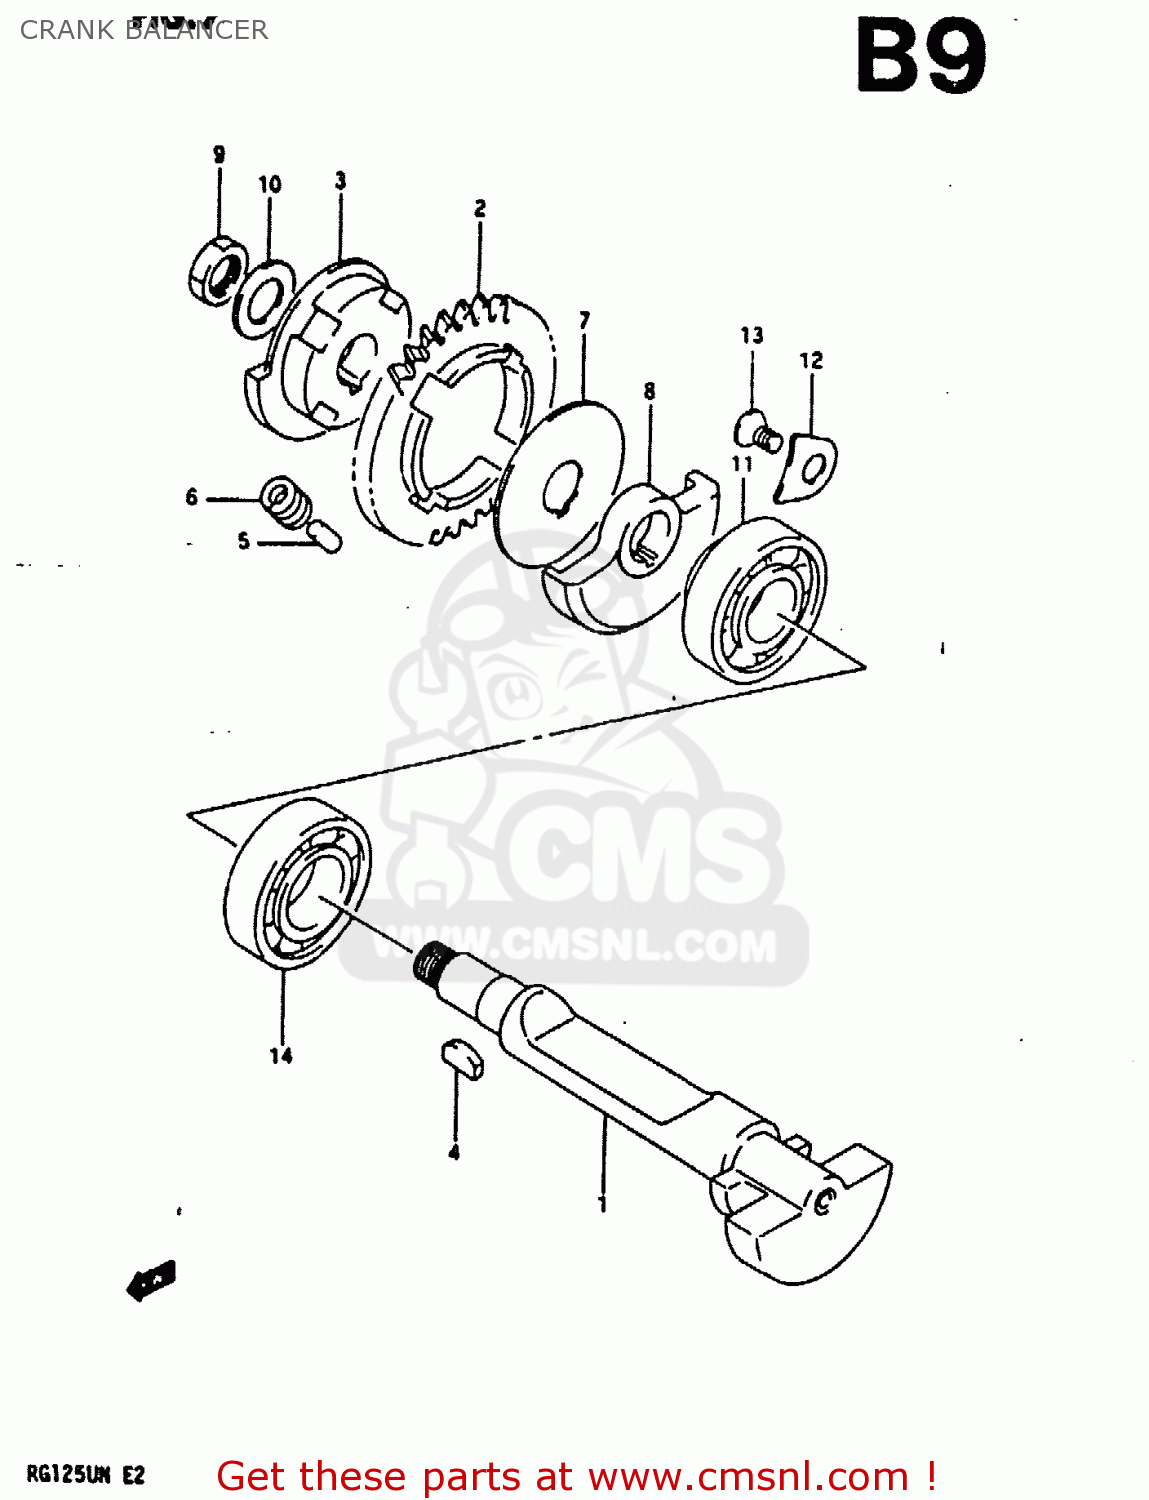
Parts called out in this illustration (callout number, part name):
1	SHAFT, CRANK BALANCER
2	GEAR, BALANCER DRIVEN
3	RACE, DRIVEN GEAR INNER
4	KEY 4MM
5	PIN(5X8.8)
6	SPRING
7	WASHER
8	WEIGHT, CRANK BALANCER RH
9	NUT
10	WASHER
11	BEARING(15X42X13)
12	RETAINER,BEARING
13	SCREW(6X12)
14	BEARING(20X42X12)
